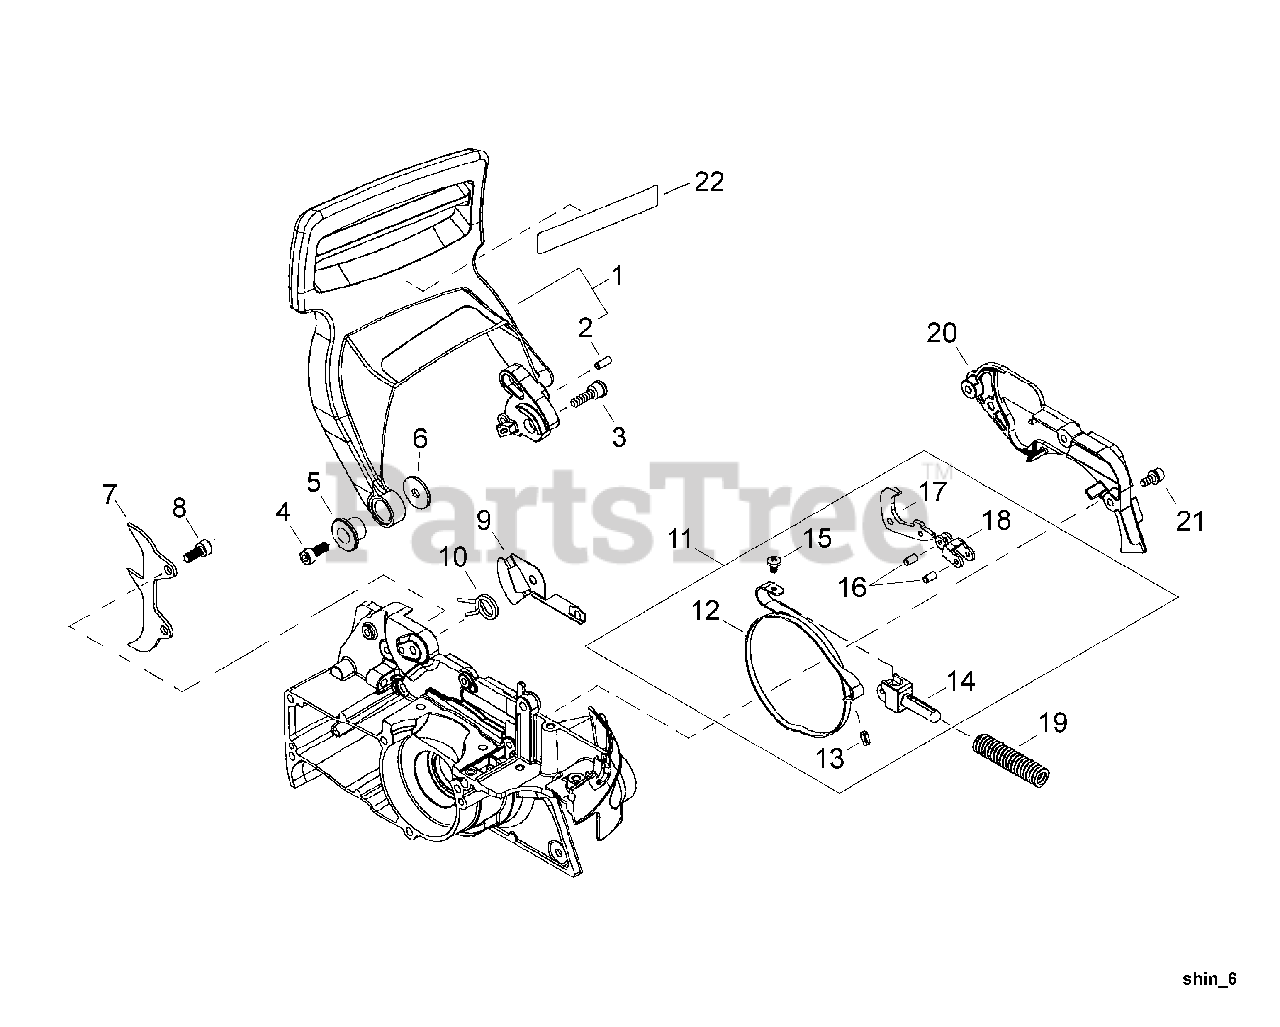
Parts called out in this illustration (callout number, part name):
1	BRAKE LEVER KIT
2	PIN - LOCATING
3	BOLT - 4X38
4	SCREW - 5X18
5	COLLAR
6	WASHER
7	SPIKE
8	SCREW - 5X12
9	PLATE
10	SPRING
11	BRAKE BAND ASSY
12	BAND, BRAKE
13	PIN - SPRING -- 4X8
14	HOLDER, BRAKE SPRING
15	SCREW - 4X10 -- TAPPING
16	TIE, CABLE - 3X11.8
17	LEVER, BRAKE
18	TIE, CABLE
19	SPRING, BRAKE
20	COVER, BRAKE
21	SCREW - 4X10
22	LABEL - CAUTION
